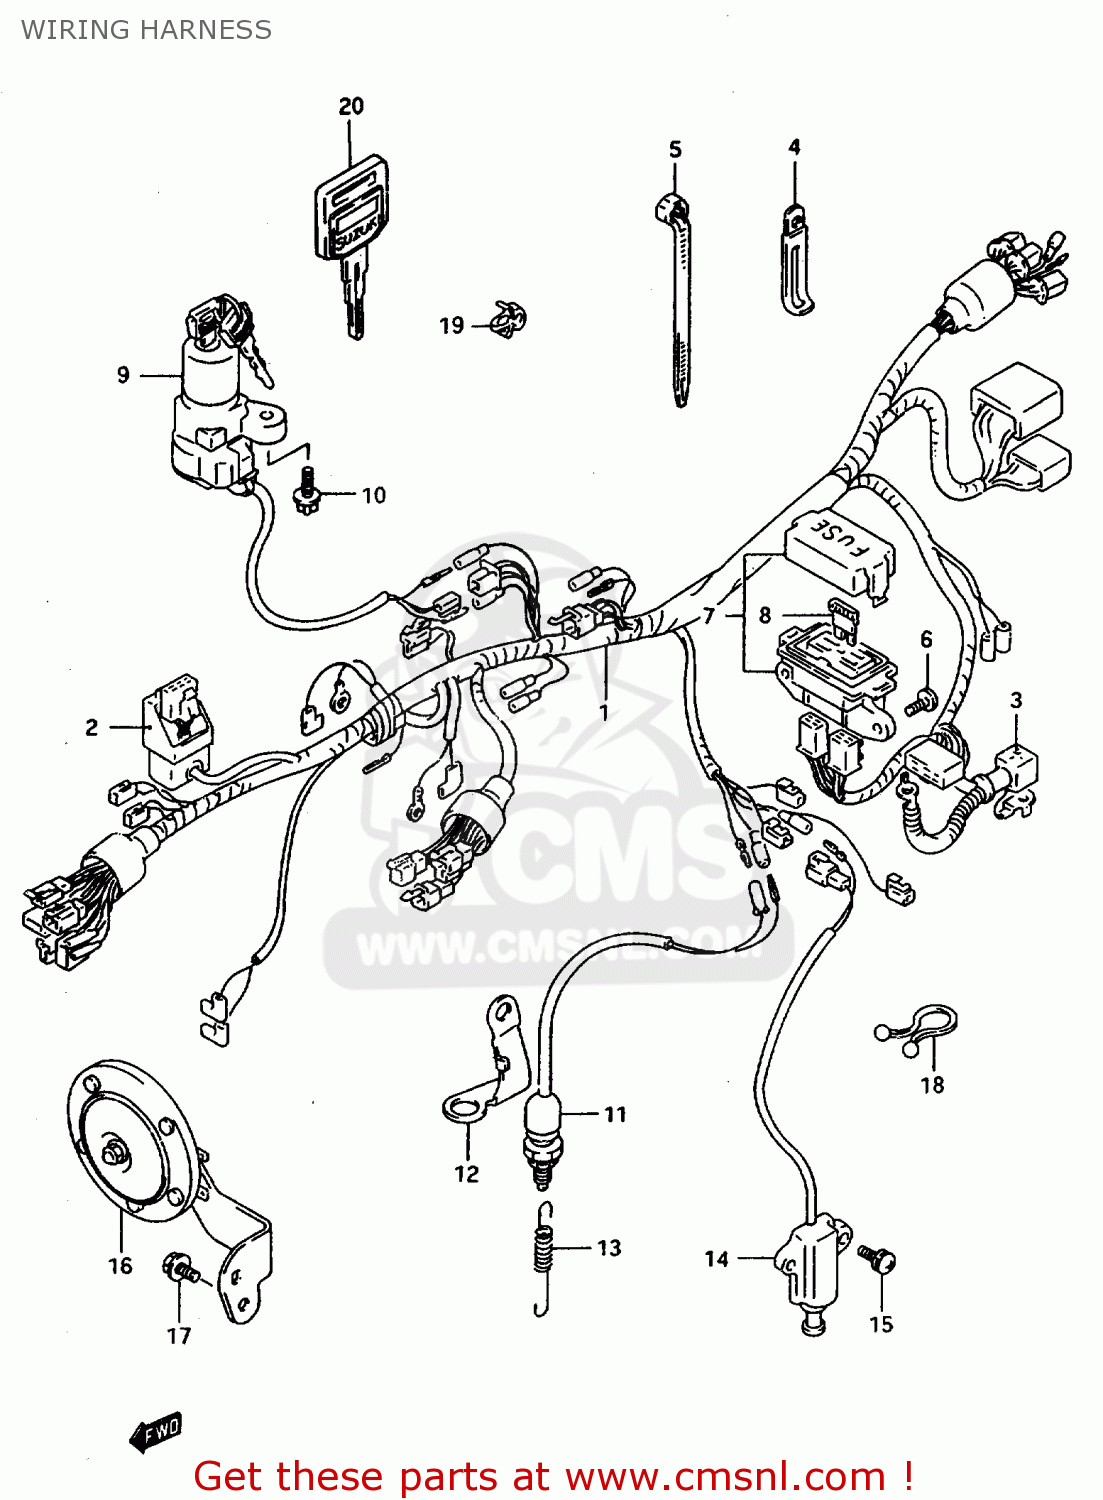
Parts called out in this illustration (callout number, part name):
1	HARNESS, WIRING
2	COVER,DECOMPRESSION CONTROL UNIT
3	CAP,BATTERY PLUS
4	CLAMP(L:65)
5	CLAMP(L:95)
6	SCREW 6X12
7	BOX ASSY,FUSE
8	FUSE(10A)
9	LOCK ASSY,STEERING
10	SCREW(6X18)
11	SWITCH ASSY,STOP LAMP
12	BRACKET,STOP LAMP SWITCH
13	SPRING
14	SWITCH ASSY,SIDE STAND
15	SCREW
16	HORN ASSY
17	BOLT
18	CLIP(ID:11.5)
19	CLAMP
20	KEY,BLANK
